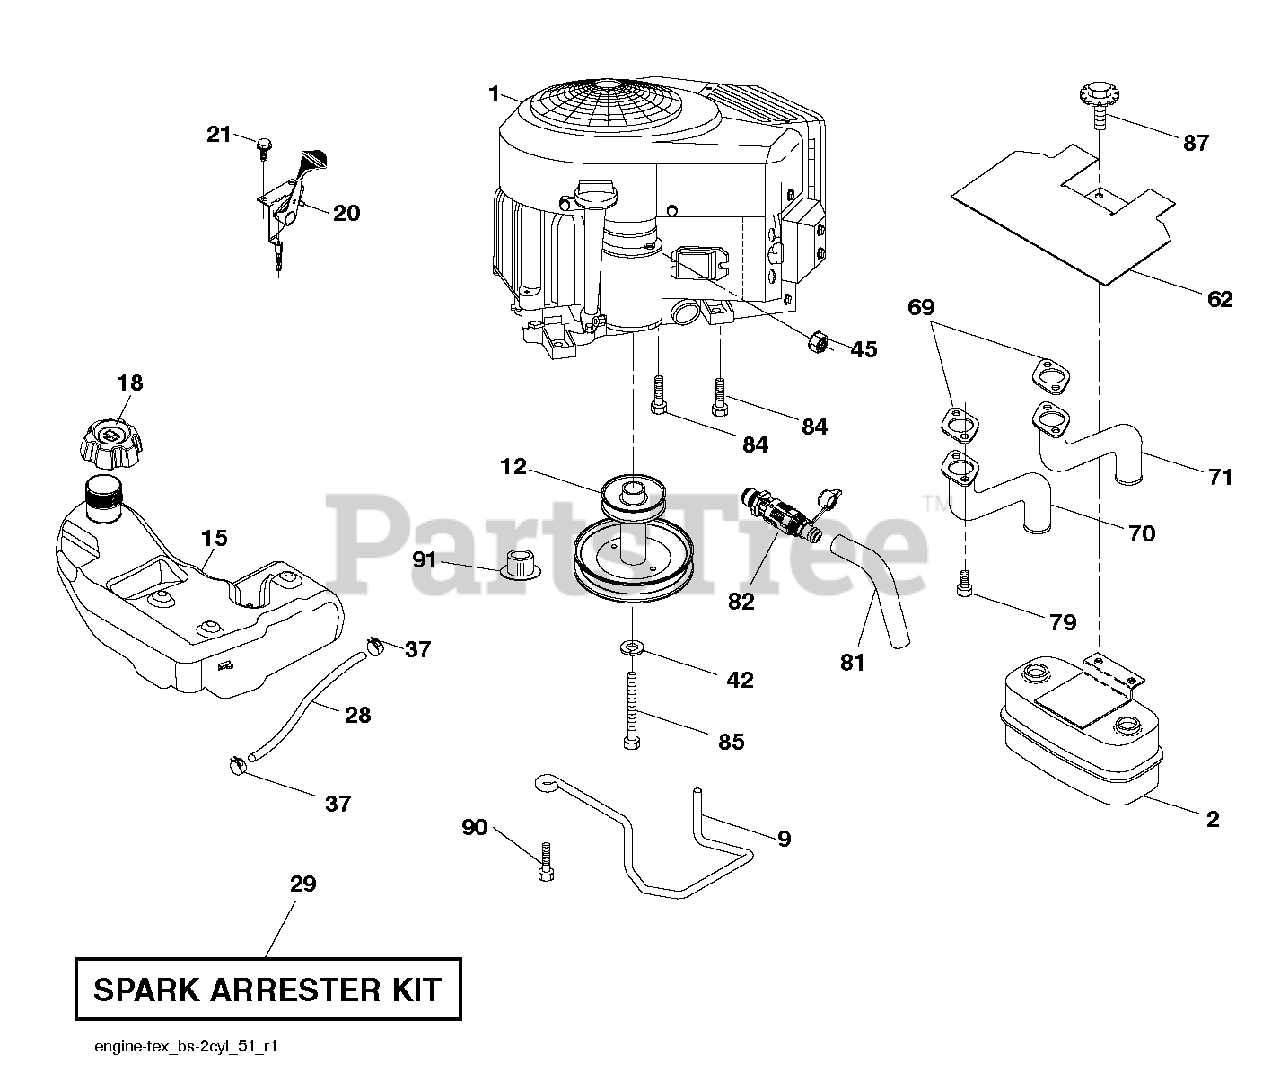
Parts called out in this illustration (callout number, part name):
2	MUFFLER.TWIN.CYL.LOW.TONE
9	KEEPER.BELT.ENGINE.4.2
12	PULLY ENGINE
15	TANK.ASSY.3.GAL.EPA
18	CAP ASM.FL.RTCHT.3"GRY.E10
20	CONTROL.TH/CK.COBRA.B&S.TWN.
21	SCREW.#10 X 0.750.BOS (2 2)
28	LINE.FUEL.64"REAR.EMIS
29	KIT.SPARK ARRESTOR(392390 B&S)
37	HOSE CLAMP
42	LOCKWASHER
45	NUT
62	SHIELD.HEAT.MUFFLER
69	GASKET.MUFFLER
70	RP.EXHAUST.TUBE.LH.BS/TWIN
71	RP.EXHAUST.TUBE.RH.BS/TWIN
79	SCREW.SOCKET.HEAD.5/16-18
81	TUBE, DRAIN OIL ASM.
82	VALUE.OIL.DRAIN
84	SCREW.3/8-16
85	BOLT HEX 7/16-20X4-1/4"
87	BOLT, 5/16-18 X 1 3/4
90	SCREW 3/8-16X1
91	BUSHING.1.375OD
